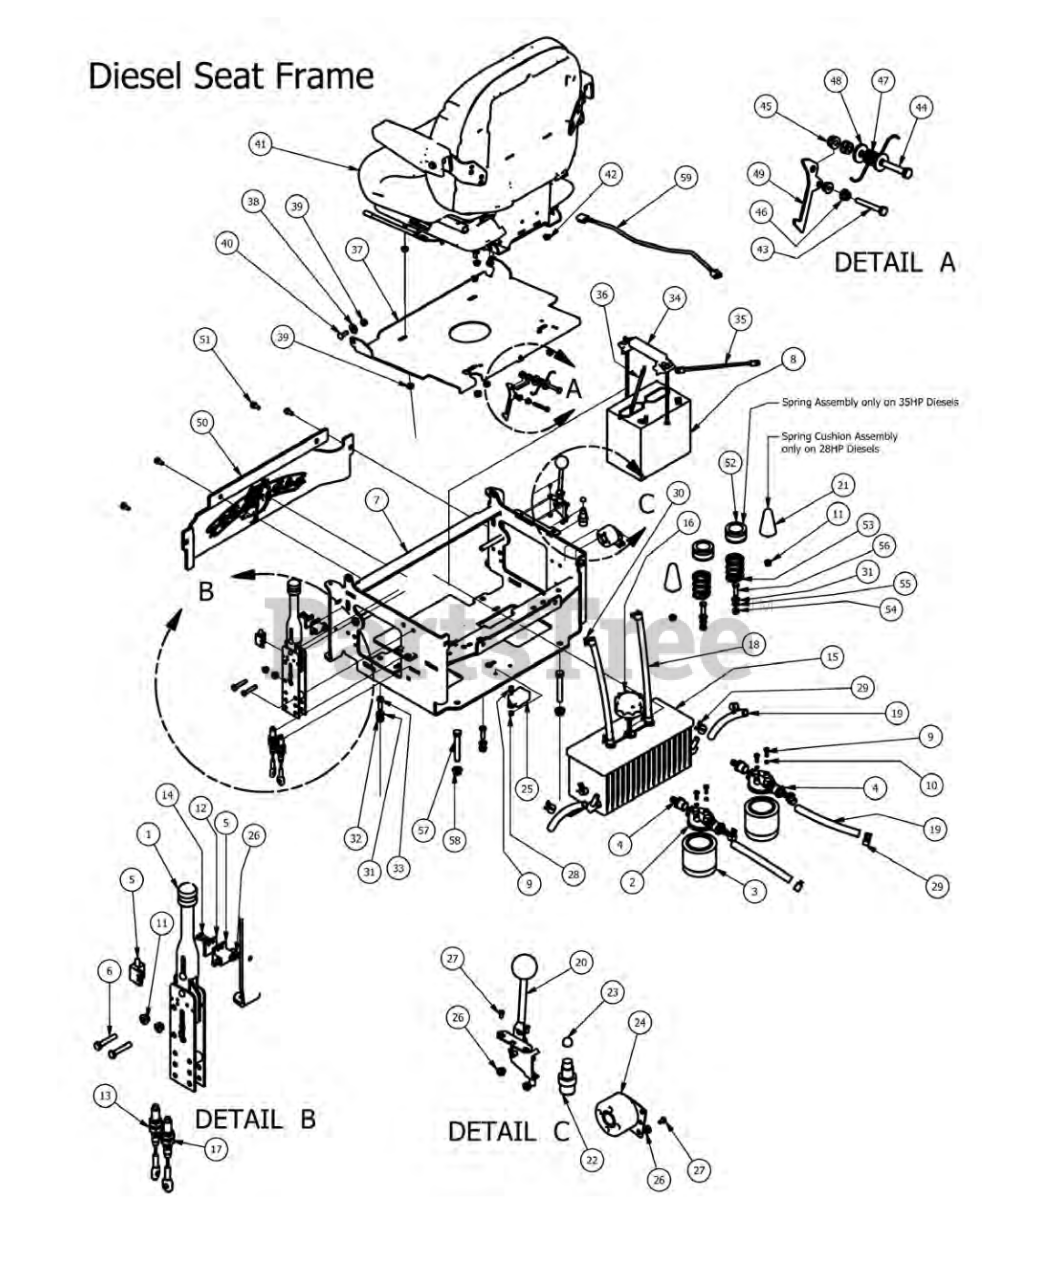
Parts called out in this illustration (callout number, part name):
1	Hand Brake Assembly
2	Filter Head
3	Hydraulic filter
4	Filter Head Fitting
6	5/16" x 1 3/4" Hex Bolt
7	2007 Diesel Seat Frame
8	Battery Diesel Models - 151
9	1/4" x 3/4" Hex Bolt
10	1/4" Lock Washer
11	5/16" Flange Nut
12	Switch Block Plastic
13	Short Brake Cable
14	1024 x 1" Allenhead Bolt
15	Aluminum Hydraulic Tank
16	Hydraulic Tank Cap
17	Long Brake Cable
18	3/8" 32" Clear Hose
19	1/2" x 9 1/4" Braided Hose
20	Throttle - Diesel
21	Spring Cushion
22	Momentary Start Switch
23	Start Switch Boot - Diesel
24	Heat Warning Piezo Buzzer
25	Auto Shut Down for Cat Diesels
26	#10 Nylock Nut
27	1024 X 5/8" Buttonhead Bolt
28	1/4" Hex Nut
29	1/2 Hose Clamp
30	3/8 hose clamp
31	3/8" Flat Washer
32	3/8" Flange Nut
33	3/8" x 1 1/4" Hex Bolt
34	Battery Hold Down
35	Black Battery Cable - Diesel
36	Red Battery Cable - Diesel
37	2006 Seat Plate
38	.360 ID Plastic Washer
39	5/16-18 Nylon Flange Nut
40	5/16" x 1" Carriage Bolt
41	Milsco Suspension Seat - AOS/Lig
42	5/16" Flange Nur
43	1/4-20 x 2 Hex Bolt
44	5/16" x1 3/4" Hex Bolt
45	5/16-18 Nylon Flange Nut
46	1/4-20 Hex Flange Nuts Zinc w/Serrations
47	Torsion Spring for Seat latch
48	.360 ID Plastic Washer
49	Seat Latch Lever
50	Cooler Cover
51	5/16 x 3/4 washer head type F screw
52	Seat Spring Cap Cover
53	Seat Spring
54	3/8" Hex Nut
55	3/8" Lock Washer
56	3/8" x 1 1/2" Hex Bolt
57	1/2 x 3 1/2 Flange Bolt Grade 8
58	1/2" Flange Nut
59	Seat Switch Adapter
